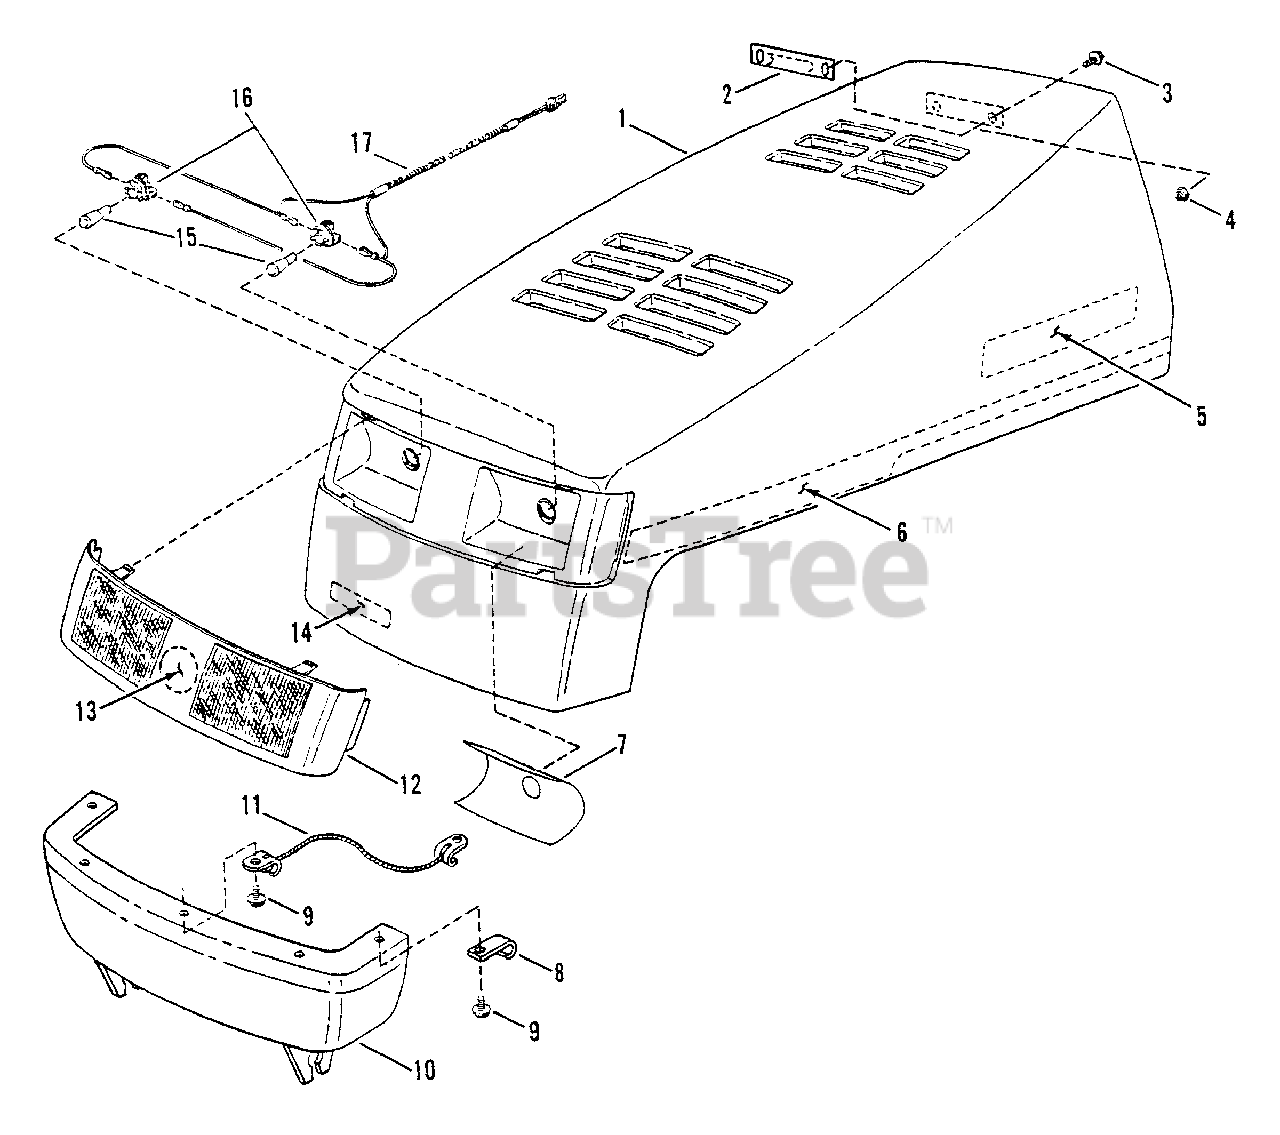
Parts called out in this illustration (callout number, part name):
1	HOOD
2	LATCH, Spring
3	SCREW, 1/4-20 x 5/8" Truss Head (Torx)
4	NUT, 1/4-20 Hex Nyloc
5	DECAL, SNAPPER 8" Molded Logo
6	DECAL, Hood, (Right Side) (33" Models)
7	DECAL, Lens (Right Side)
8	CLIP "J"
9	SCREW, M4.8 x 1.59 x 16mm Special
10	BUMPER, Front
11	LANYARD, Hood
12	LENS, Clear
13	DECAL, Molded Medallion, Convertible Mower
14	DECAL, SNAPPER, 4" Molded Logo
15	BULB, Headlights
16	SOCKET, Headlight Bulb
17	HARNESS, Headlight Wiring
